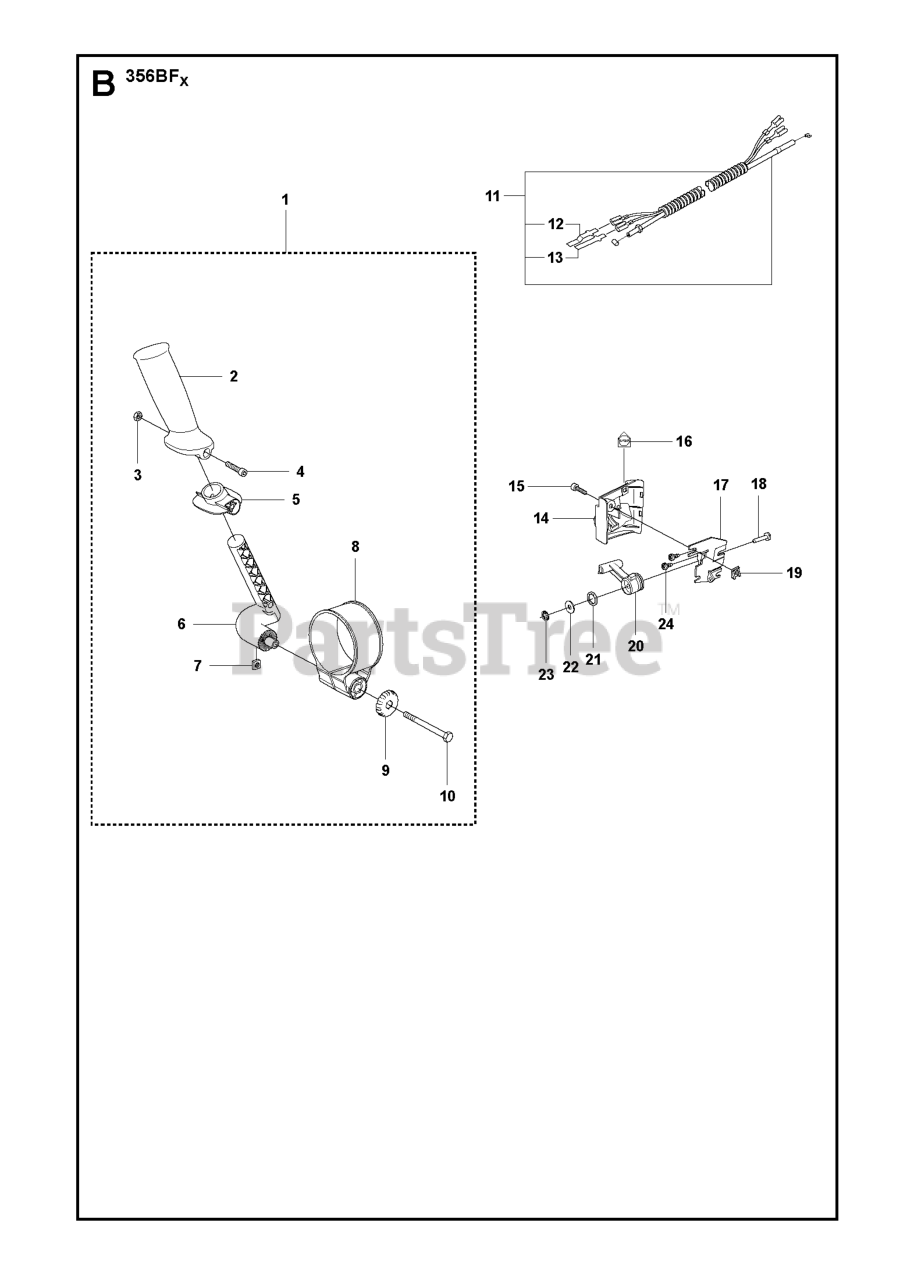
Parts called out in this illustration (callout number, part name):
4	SCREW
6	BRACKET
11	CABLE ASSY
21	SPRING RUBBER
